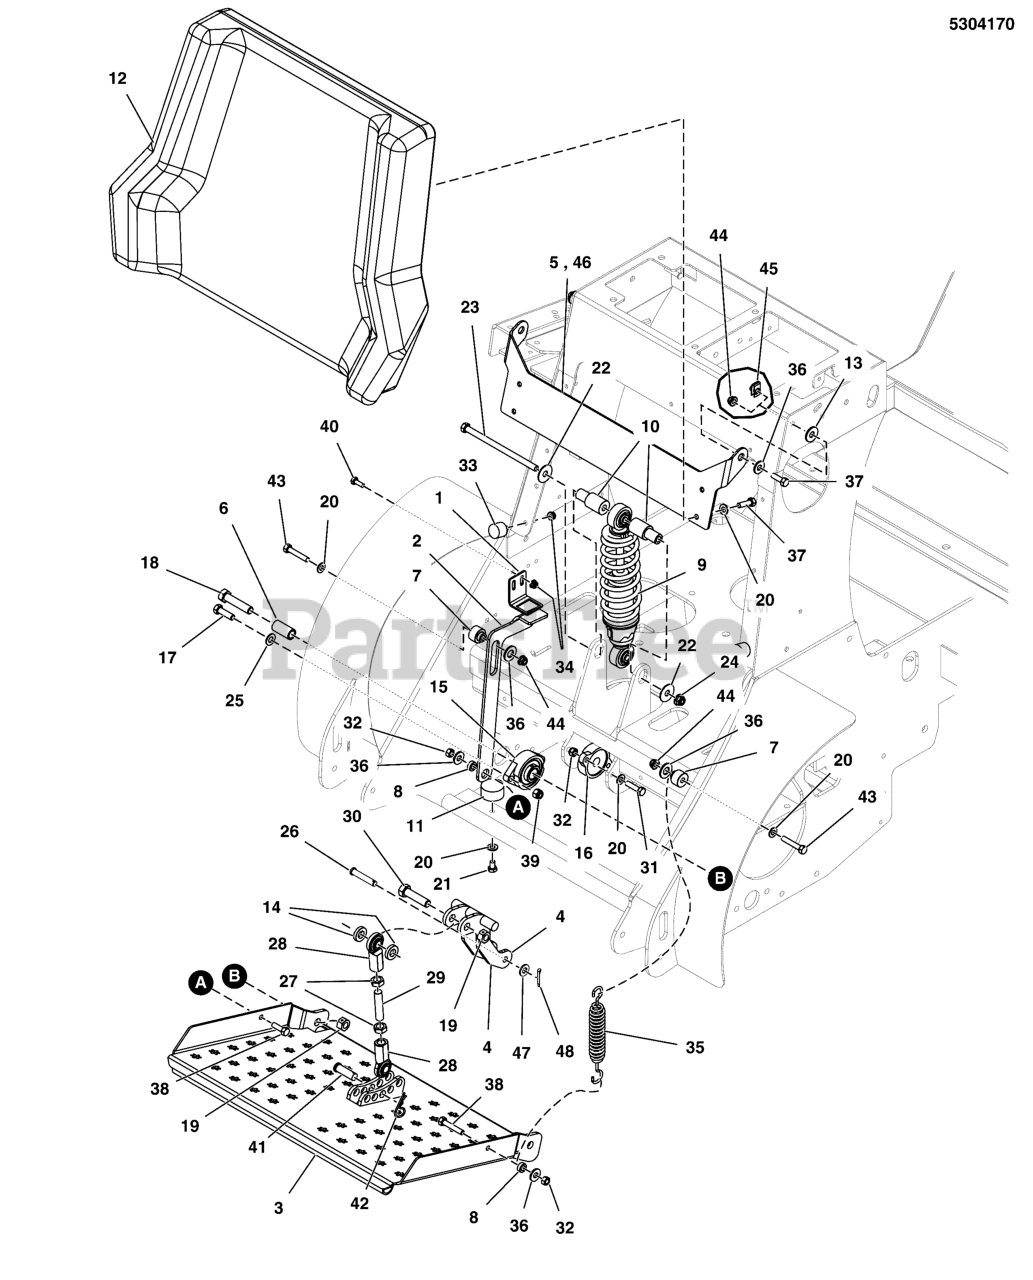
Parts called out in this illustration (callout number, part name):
1	PLATE, OPC, STAND ON - BLK
2	PLATE, OPC LINK, STAND ON - BLK
3	WELD, STAND ON PLATFORM - BLK
4	WELD, SUSPENSION LINK - BLK
5	PLATE, PAD MOUNT, STAND ON - RED
6	SPACER, .52 X .74 X 1.50, CZ
7	SPACER, .328 X 1.0 X .85, CZ
8	SPACER, .33 X .63 X .25, CZ
9	SHOCK / SPRING ASSEMBLY
10	SPACER, STEP, .39 X 1.00 X .69, CZ
11	BUMPER, RUBBER
12	KNEE PAD, STAND-ON
13	WASHER, 5/16" Fender
14	SPACER, .52 X 1.00 X .22, PM, CZ
15	BEARING, FLANGE
16	BEARING-FLANGE, 5/8
17	BOLT, 3/8-16 X 1-1/4" GD5 CZ
18	BOLT, 1/2-13 X 2-1/4" GD5 CZ
19	NUT, 1/2-13 Hex Side Lock
20	WASHER, 5/16" SAE
21	BOLT, 5/16-18 X 3/4 GD5
22	WASHER, 3/8" Fender
23	BOLT, 3/8-16 X 5-1/2" GD5 CZ
24	NUT, 3/8 - 16 HEX NYLOCK FLANGE
25	WASHER, 3/8 SAE
26	PIN, Clevis
27	NUT, 1/2-20 Hex Jam
28	JOINT-BALL .500-20 THD .500ID, CLR ZINC
29	ROD, THREADED, 1/2-20 X 2.25
30	BOLT, 1/2-13 X 2" GD5 CZ
31	BOLT, 5/16-18 X 1" GRD5 YZ
32	NUT, 5/16-1/8, HEX, CNTR LK, ZINC PHOS/OIL
33	BUMPER, RUBBER, 1/4-20
34	NUT, 1/4-20 Hex Nylock Flange
35	SPRING-EXT, 1.04 ODX6.935LGX.148WR, BLK
36	WASHER, 5/16" USS
37	BOLT, 5/16-18 X 1" GRD5 YZ
38	SCREW, TRUSS HD TORX DR5/16-18X0.875 BLK
39	NUT, 3/8-16 HEX NYLON LOCK
40	BOLT,1/4-20X0.750,GR5,STD NECK,SQ,ZC/CL
41	PIN, CLEVIS, 1/2 X 1-1/2, PLATED
42	PIN, SURE LOCK COTTER, .09 X .75, CZ
43	BOLT, 5/16-18 X 1-3/4" GD5 YZ
44	NUT, 5/16-18 HEX NYLOCK FLANGE NUT
45	BODY CLIP, 5/16-18-7GA MATERIAL
46	PLATE, PAD MOUNT, SRS - RED
47	WASHER, 3/8" GR. 9 FLAT
48	* PIN, COTTER, 1/8" X 3/4
